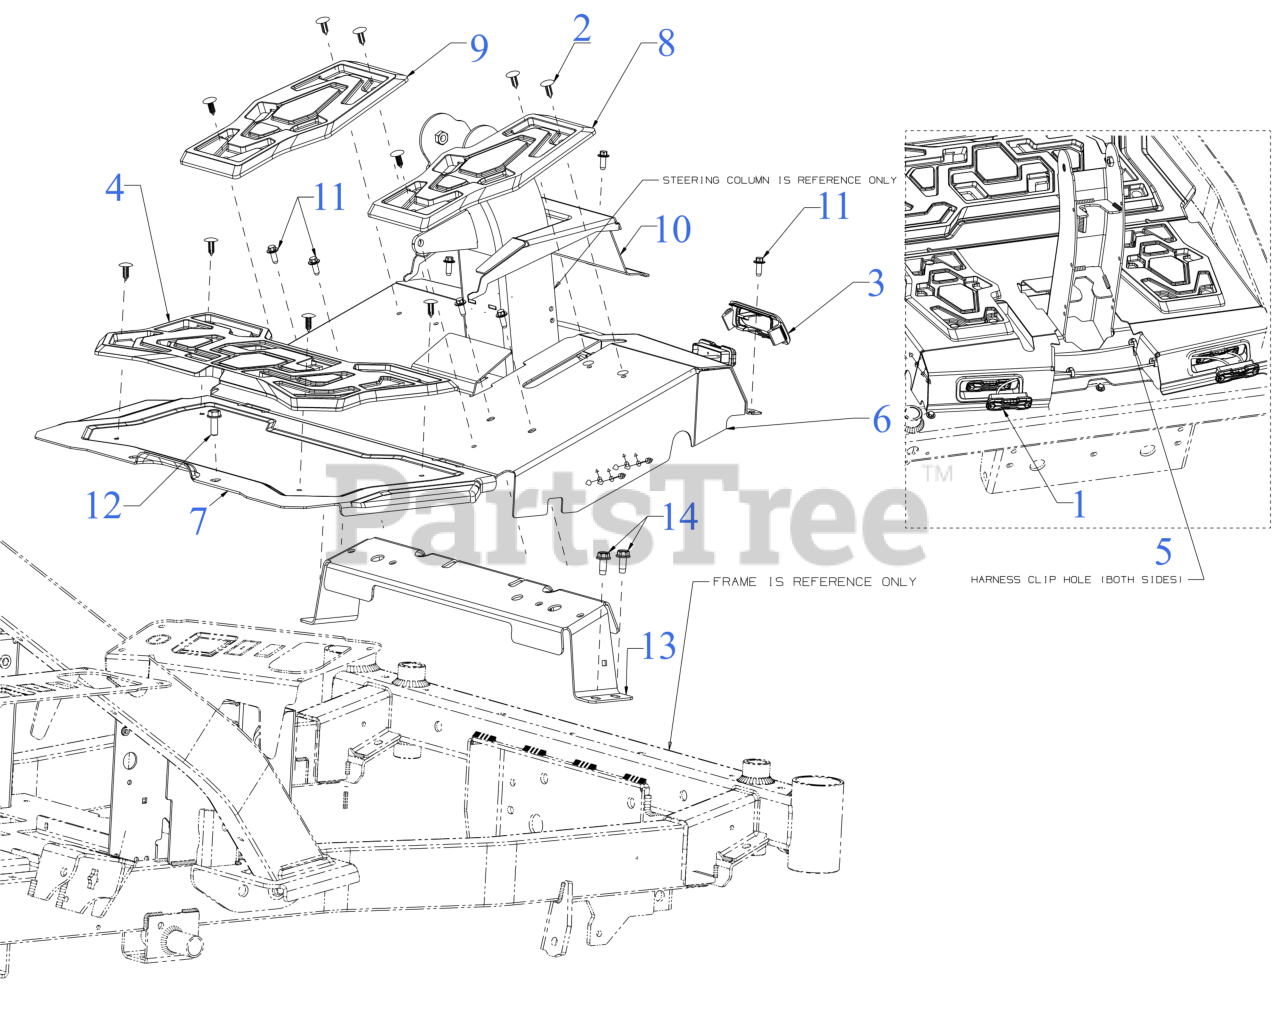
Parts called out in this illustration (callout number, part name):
1	HEADLIGHT HARNESS (W/LED)
2	RATCHET CLIP .250
3	LIGHT BEZEL
4	FLOORBOARD MAT (LOWER)
5	HARNESS CLIP
6	FOOTREST
7	FLOORBOARD
8	FLOORBOARD MAT (UPPER)
9	FLOORBOARD MAT (UPPER)
10	MID FOOTREST
11	SCREW M6-1 x .625
12	SCREW 5/16-18 x .875 GR5 HXFLG HD
13	STEERING SUPPORT BRACKET
14	SCREW 5/16-18 x .750
